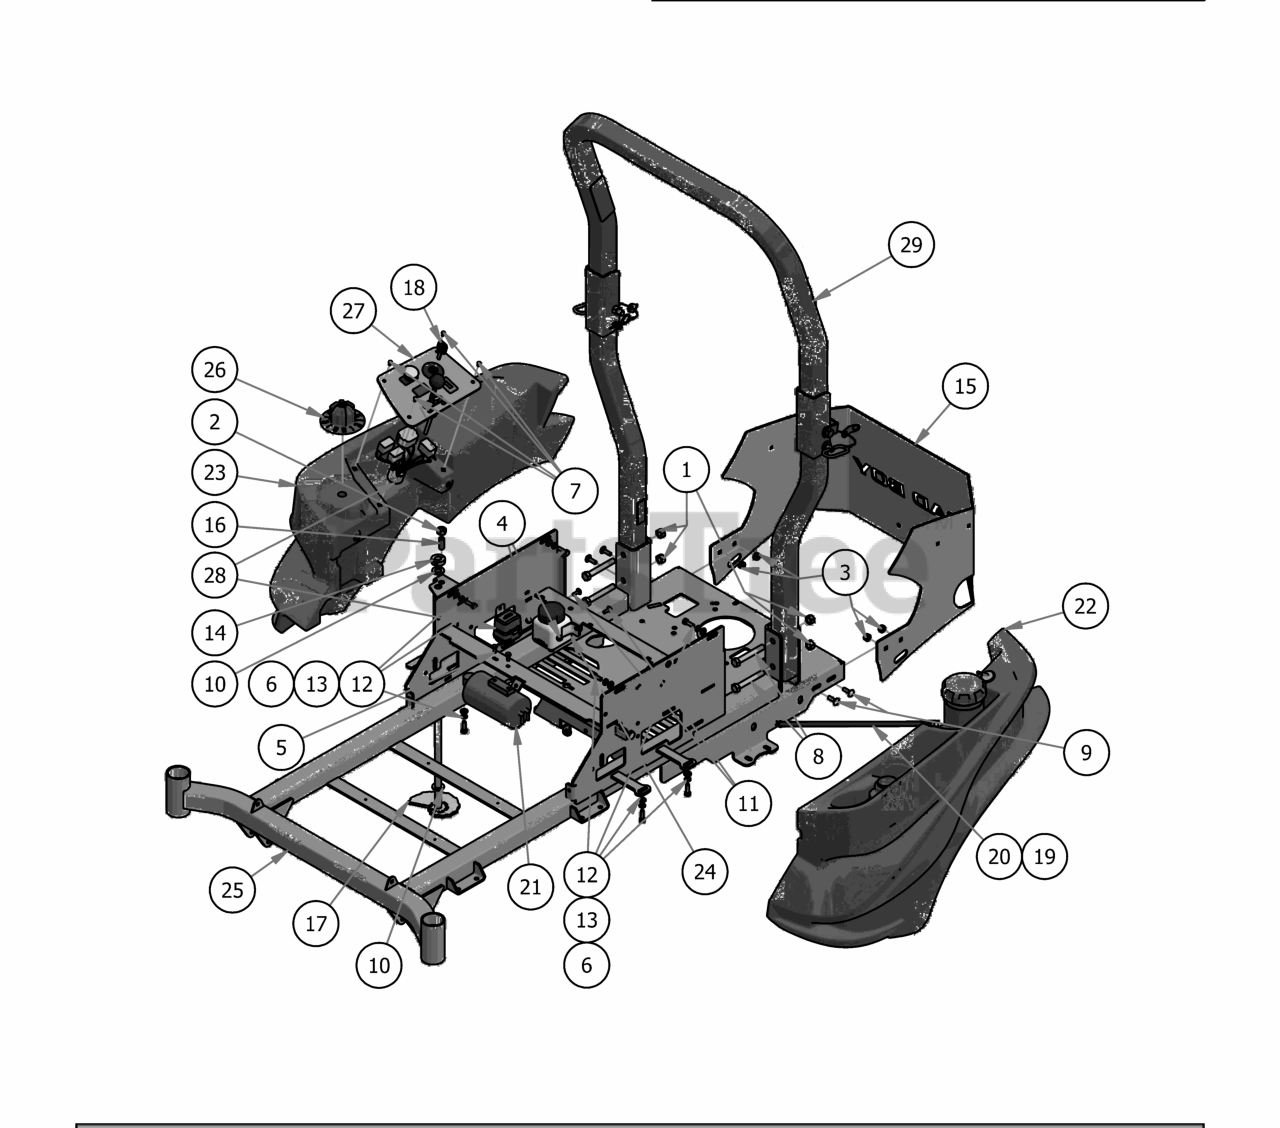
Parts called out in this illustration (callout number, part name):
1	1/2" Center Lock Nut
2	1/2" Hex Nut
3	5/16-18 Nylon Flange Nut
4	1/4" Nylock Nut
5	M6-1.0 X 16MM Hex Bolt
6	5/16" x 1" Bolt
7	10-32 x 3/8" Button Socket Head Bolt
8	1/2-13 x 3 1/2 GR 5 Hex Bolt
9	5/16" x 1" Carriage Bolt
10	.630 ID x 1.122 OD x .142 THK Plastic Washer
11	1/4" x 3/4" Carriage Bolt
12	5/16" Flat Washer
13	5/16" Lock Washer
14	5/8" Split Collar
15	2017 ZT Rear Plate
16	Dial Rod Plunger
17	ZT Deck Height Bar Assembly
18	Ignition Key
19	Vanguard Fuel Line Assy-37"
20	2015 ZT KawaFuel Line Assy-22"
21	ZT/Mav EPA Cannister Assy
22	Left Fuel Tank
23	Right Side Console
24	Hydro Tank Assembly
25	2018 Compact Outlaw Frame
26	MZ/ZT Deck Height Dial
27	2019 ZT/Maverick Control Panel Assembly
28	Wiring Harness
29	2016 2x2 ROPS
